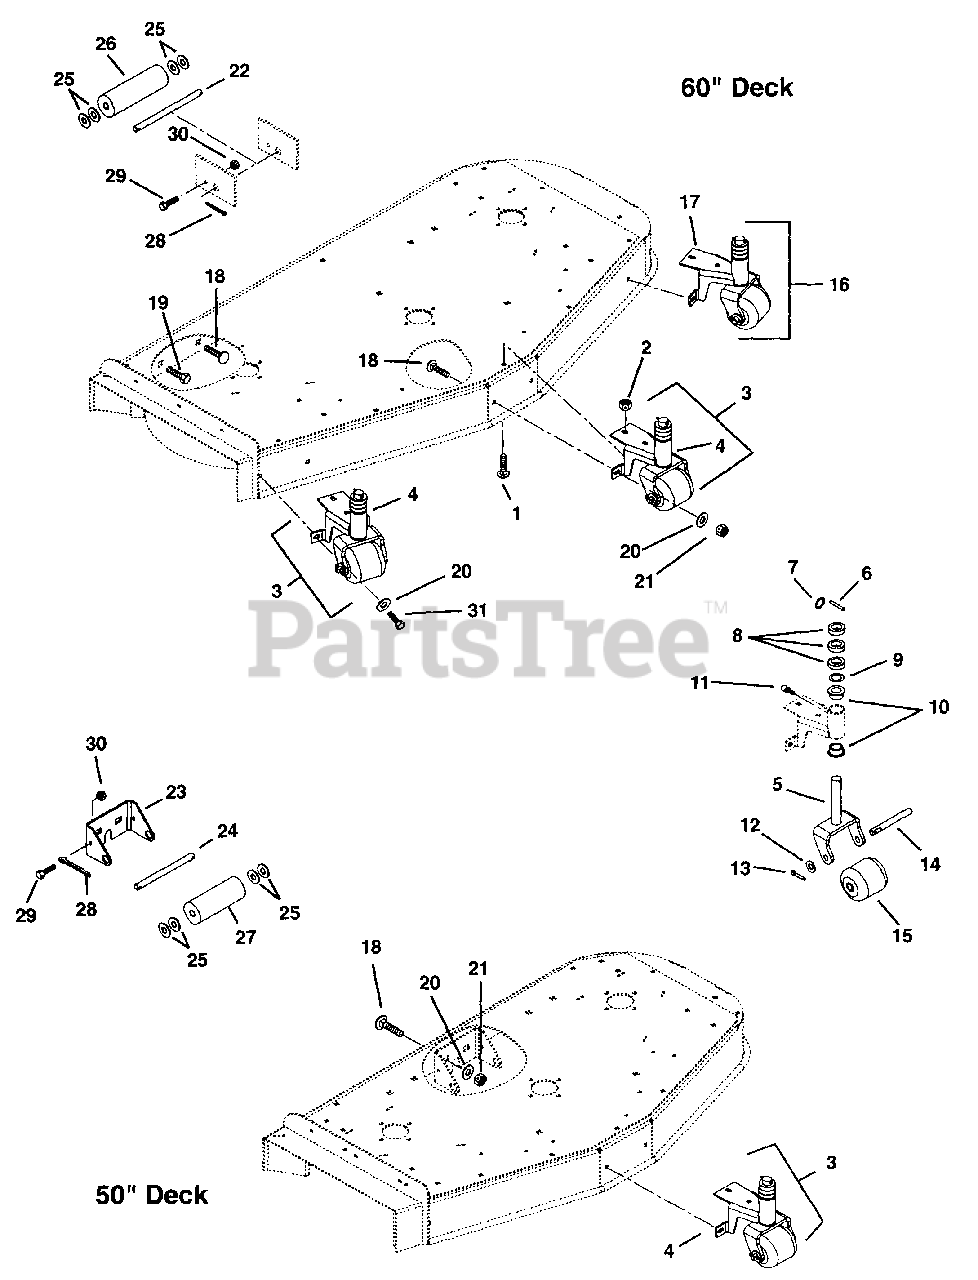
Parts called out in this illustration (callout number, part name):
1	Bolt-Round Head Square Neck .38-16 x 1.00 Grade 2 (60" Deck)
1	Bolt-Round Head Square Neck .38-16 x 1.00 Grade 2 (50" Deck)
2	Nut-Locking-Nylon .38-16 (60" Deck)
2	Nut-Locking-Nylon .38-16 (50" Deck)
3	Assembly, Roller Bracket (60" Deck)
3	Assembly, Roller Bracket (50" Deck)
4	Weldment-Roller Bracket
5	Weldment-Roller Fork
6	Pin-Clevis .19 x 2.00
7	Kickout Ring
8	Bushing-Sleeve 1.04 x 1.75 x .500
9	Washer-Hardened Thrust 1.00 x 1.55 x .03
10	Bushing-Flange 1.020 x 1.385 x .75 x 1.75
11	Fitting-Lube .25-28 Taper
12	Washer-Flat Steel .656 x 1.31 x .095
13	Pin-Cotter .25 x 1.00
14	Shaft, Castor
16	Assembly, Roller Bracket-Left Front (60" Deck)
17	Weldment-Roller Bracket-Left Front (60" Deck)
18	Bolt-Round Head Square Neck .38-16 x 1.00 Grade 2 (60" Deck)
18	Bolt-Round Head Square Neck .38-16 x 1.00 Grade 2 (50" Deck)
19	Bolt-Hex .38-16 x 1.00 Grade 5 (60" Deck)
20	Washer-Flat-Steel .38 x .875 x .083 (60" Deck)
20	Washer-Flat-Steel .38 x .875 x .083 (50" Deck)
21	Nut-Locking-Nylon .38-16 (60" Deck)
21	Nut-Locking-Nylon .38-16 (50" Deck)
22	Shaft, Center Roller (60" Deck)
23	Bracket, Roller (50" Deck)
24	Rod (50" Deck)
25	Washer-Flat-Steel .656 x 1.31 x .095
26	Roller, Gage (60" Deck)
27	Roller, Gage (50" Deck)
28	Pin-Cotter .25 x 2.00
29	Bolt-Hex .25-20 x .75 Grade 5
30	Nut-Locking-Center .25-20
31	Bolt-Hex .31-18 x 1.00 Grade 2 (60" Deck)
